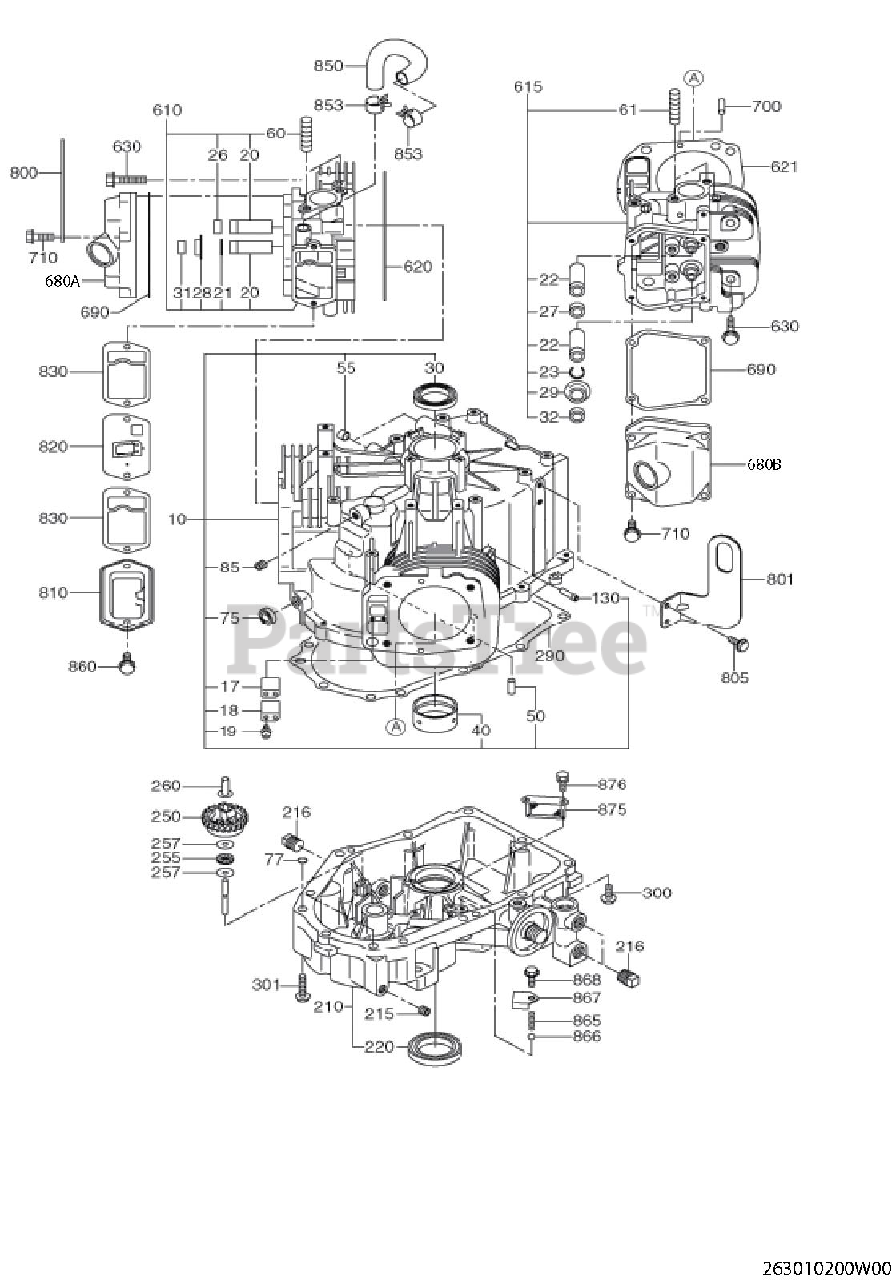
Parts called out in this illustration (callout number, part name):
18	RETAINER PLATE
19	SCREW AND WASHER AY
20	VALVE GUIDE
22	VALVE GUIDE
26	SEAL-EXH VALVE
27	SEAL-EXH VALVE
28	RETAINER PLATE
29	RETAINER PLATE
31	OIL SEAL EXH VALVE
32	OIL SEALEXH VALVE
210	MAINBEARING COVER CP
250	GOVERNOR GEAR CP
255	THRUST BEARING
260	GOVERNOR SLEEVE CP
290	GASKET (M.B. COVER)
610	CYLINDER HEAD 1 CP
615	CYLINDER HEAD 2 CP
620	GASKET 1 (CYL. HEAD)
621	GASKET 2 (CYL. HEAD)
680	ROCKER COVER
690	GASKET (ROCKET COVER)
810	BREATHER COVER
820	BREATHER PLATE CP
830	GASKET (BREATHER PLATE)
867	RETAINER PLATE
